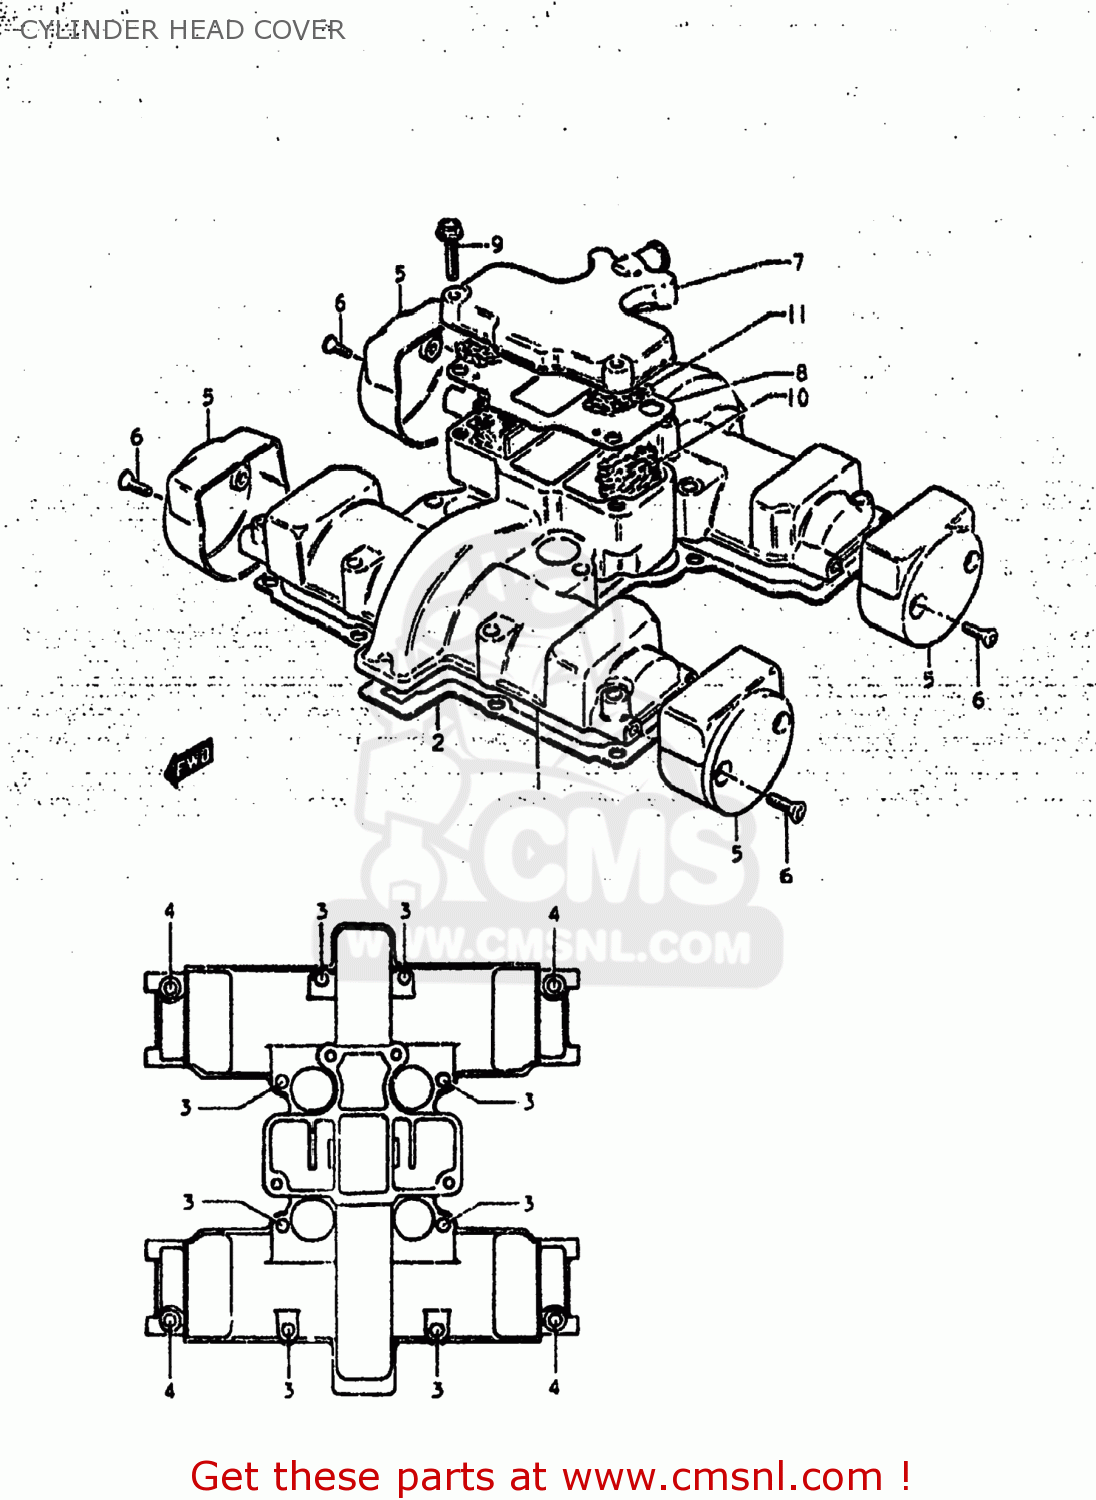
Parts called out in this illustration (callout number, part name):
1	COVER,CYLINDER HEAD
2	GASKET,CYLINDER HEAD COVER (MCA)
3	BOLT
4	BOLT
5	CAP,CYLINDER HEAD COVER
6	SCREW
7	COVER,BREATHER
8	GASKET (MCA)
9	BOLT
10	COVER,BREATHER
11	SEPARATOR,OIL BREATHER
